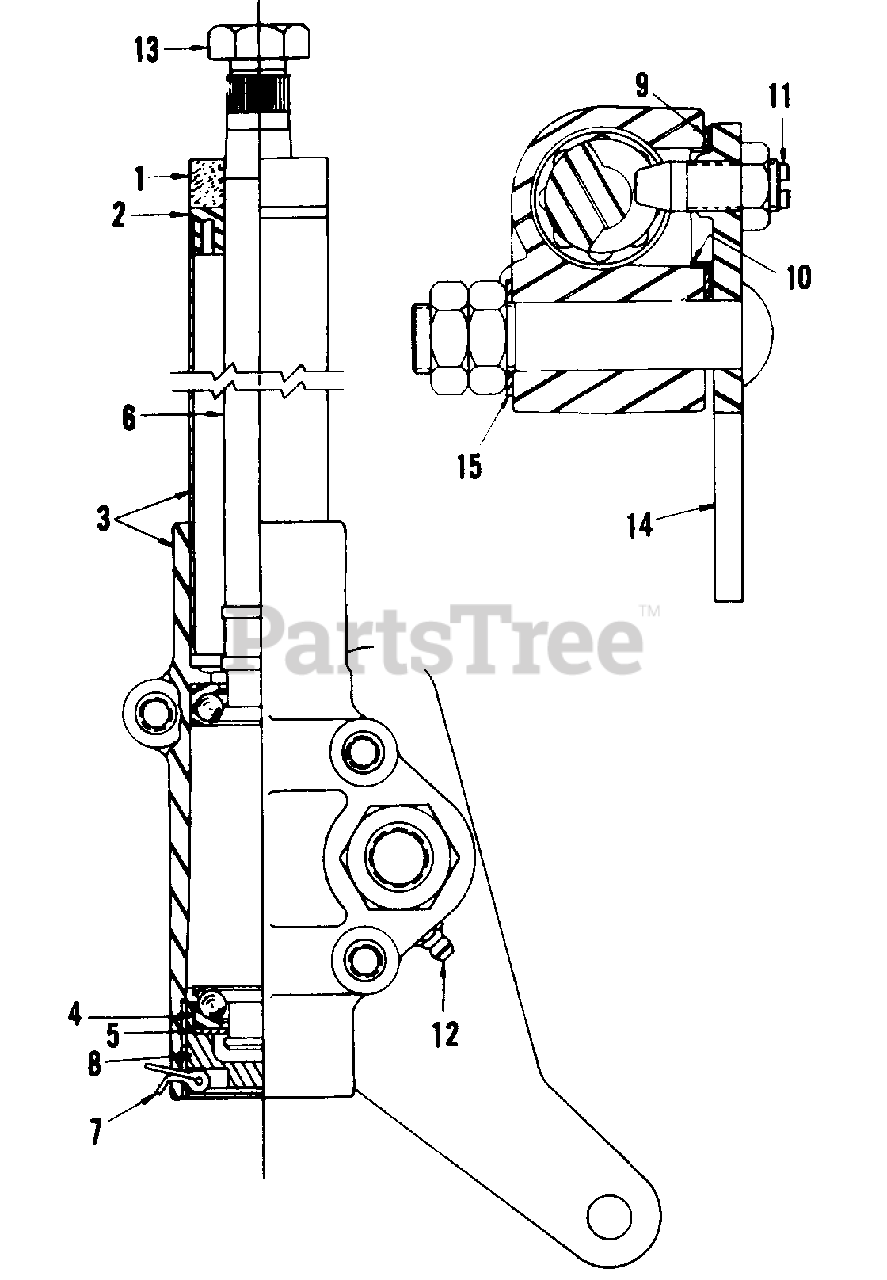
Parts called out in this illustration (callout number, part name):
1	Seal, Steering
2	Bearing, Column Upper
3	Tube Assy, Housing
4	Kit, Ball Cup
5	Washer, Belleville
7	Pin, Cotter, 1/8 X 1.25 Lg
8	Plug, Adjusting
11	Screw, Cam Follower
12	Fitting, Lube, 1/4 Drive
13	Nut, Steering Wheel Jam
14	Level & Bolt Assy
15	Washer, Flat
